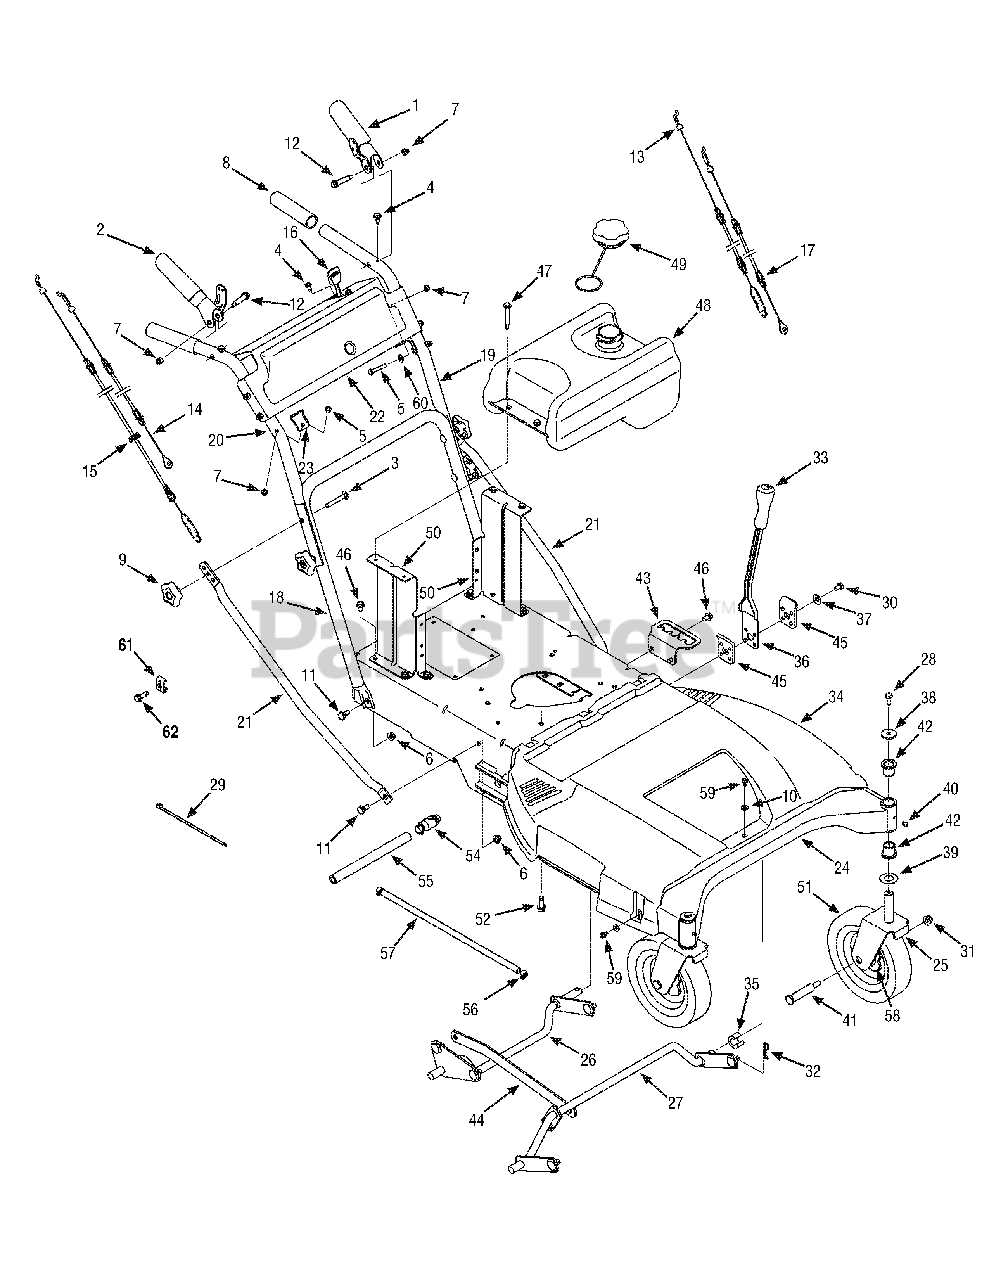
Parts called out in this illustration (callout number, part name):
1	Lever Assembly: LH
2	Lever Assembly: RH
3	Screw, Carriage: 5/16-18 x 2.25"
4	Screw, TT: 1/4-20 x 0.500"
5	Screw, HH Cap: 1/4-20 x 1.50"
6	Nut, Flange Lock: 5/16-18
7	Nut, Lock Cap: 1/4-20
8	Grip: 1.0" ID x 5.0" Lg
9	Star Knob 5/16-18
10	Washer, Flat: .25 x .63 x .0515
11	Screw, Shoulder: .435" x .178-5/16
12	Screw, Shoulder: .375" x 1.355" x 1/4-20
13	Cable, Clutch Wheel
14	Cable, Brake, Transmission: RH
15	Cable, Clutch Deck
16	Cable, Throttle/Choke: 38" x 1.1" Ext
17	Cable, Brake, Transmission: LH
18	Lower Handle
19	Upper Handle: LH
20	Upper Handle: RH
21	Brace Tube
22	Handle Panel
23	Cable Mount Bracket: RH
23	Cable Mount Bracket: LH
24	Frame Assembly
25	Caster Wheel Bracket Assembly
26	Deck Lift Assembly: RR
27	Deck Lift Assembly: Front
28	Screw, HH Cap: 5/16-24 x .750"
29	Cable Tie,3/16 x .05 x 7.4
30	Screw, HH Cap: 5/16-18 x .50"
31	Nut, Flange Lock: 3/8-16
32	Click Pin: .092" x 1.64"
33	Handle Grip 1/2"
34	Belt Cover 33" Wide Cut Mower
35	Snap Spacer: .63" ID x .75" LG
36	Deck Height Lever
37	Washer, Bell: .340" x .872" x .060"
38	Washer, Flat: .330" x 1.25" x .120"
39	Washer, Flat: .760" ID x 1.50" OD
40	Lube Fitting: 3/16: LNC #70
41	Bolt, Shoulder: .625" x 2.515" x 3/8-16
42	Flange Bearing: .760" x .941" x 1.0"
43	Height Adjustment Bracket
44	Link Pivot Bracket
45	Lever Pivot Bracket
46	Screw, TT: 5/16-18 x .625"
47	Screw, Shoulder: .3175" x .188" x 1/4-20
48	Fuel Tank, 2 Gal.
49	Fuel Cap
50	Fuel Tank Mounting Bracket
51	Wheel, 8" x 1.75"
52	Screw, TT: 3/8-16 x 1.25"
54	Oil Drain
55	Oil Drain Hose
56	Hose Clamp
57	Fuel Hose
58	Flange Bearing, .635"
59	Screw, 1/4-14 x .625
60	Washer, Bell: .265" x .75" x .062"
61	Casing Clamp
62	Screw, 10-32 X .625
